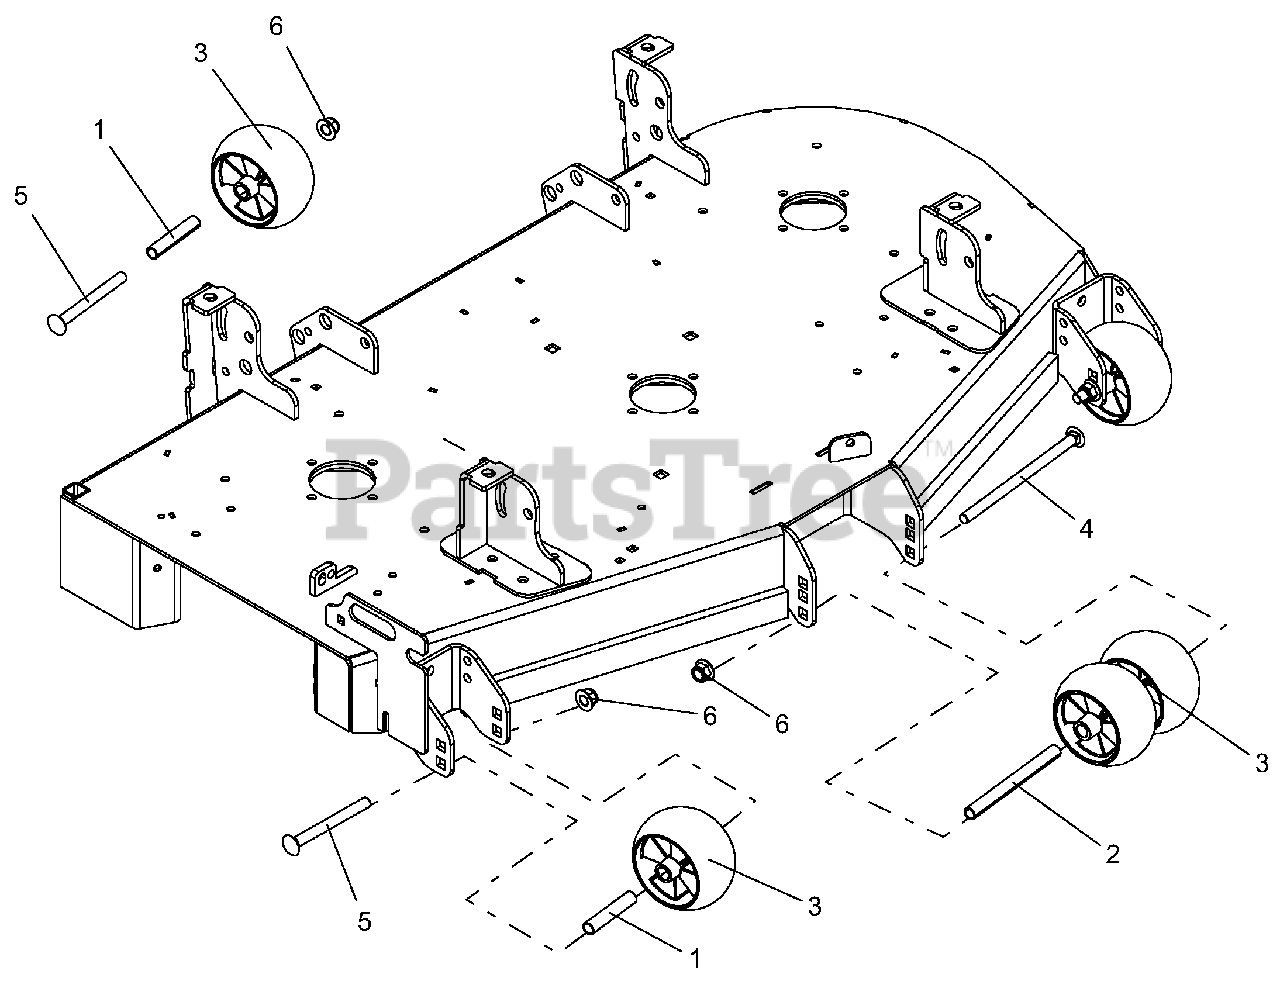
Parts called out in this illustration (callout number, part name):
1	SPACER, .510X.625X3.35
2	SPACER, .510X.625X6.70
3	ANTI-SCALP WHEEL - 5X3 CTR
4	BLT-RDHDSQNK .50-13X8.50 Y
5	BLT-RDHDSQNK .50-13X5.00 G5 YWZC
6	NUT-LK-NYL-FLG .50-13 YWZC
